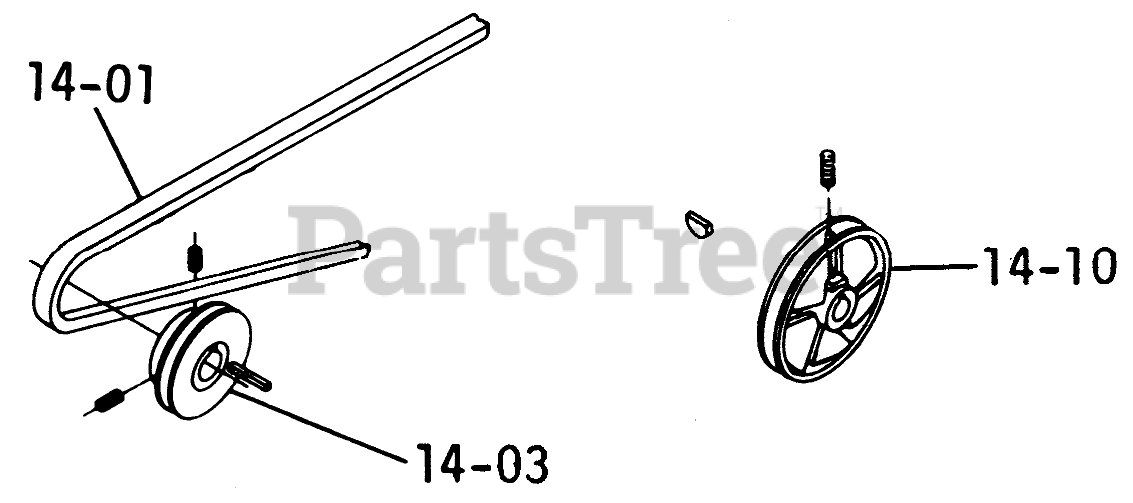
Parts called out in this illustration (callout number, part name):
14-01	V BELT
14-03	PULLEY
14-10	Pulley Trans
